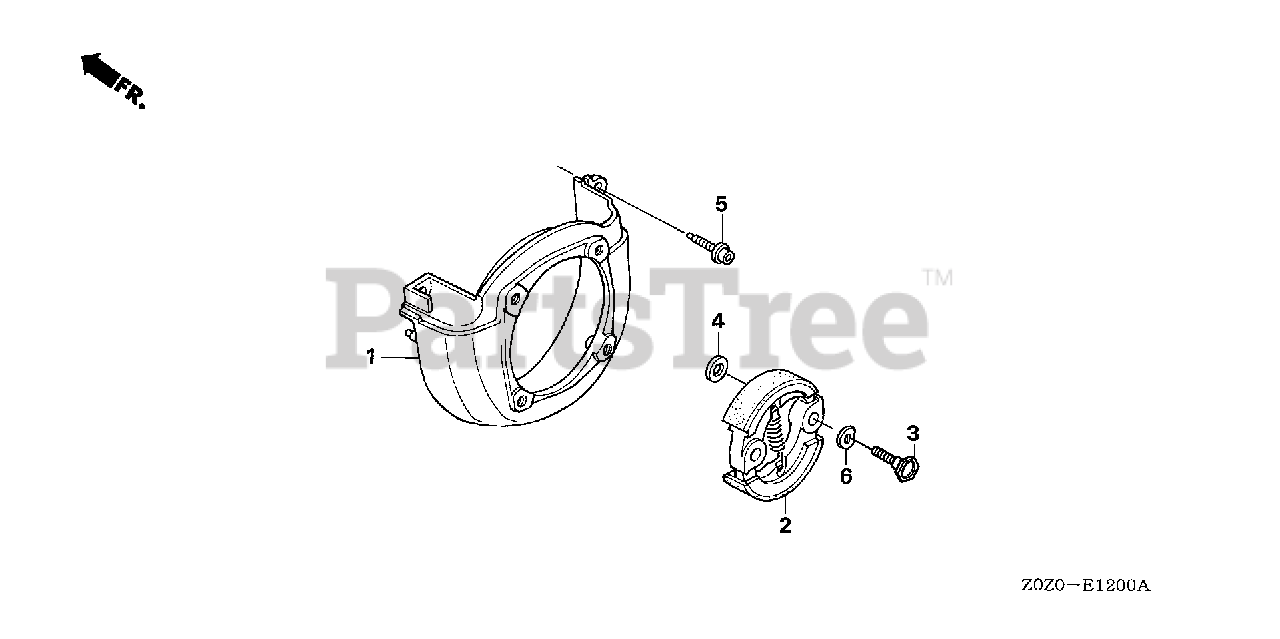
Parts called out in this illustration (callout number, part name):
1	COVER, FAN
2	CLUTCH ASSY.
2	CLUTCH ASSY. (ACRO)
3	BOLT, CLUTCH (8MM)
4	WASHER, CLUTCH (8X17)
5	BOLT, SOCKET (5X20)
6	WASHER, WAVE (10MM)
